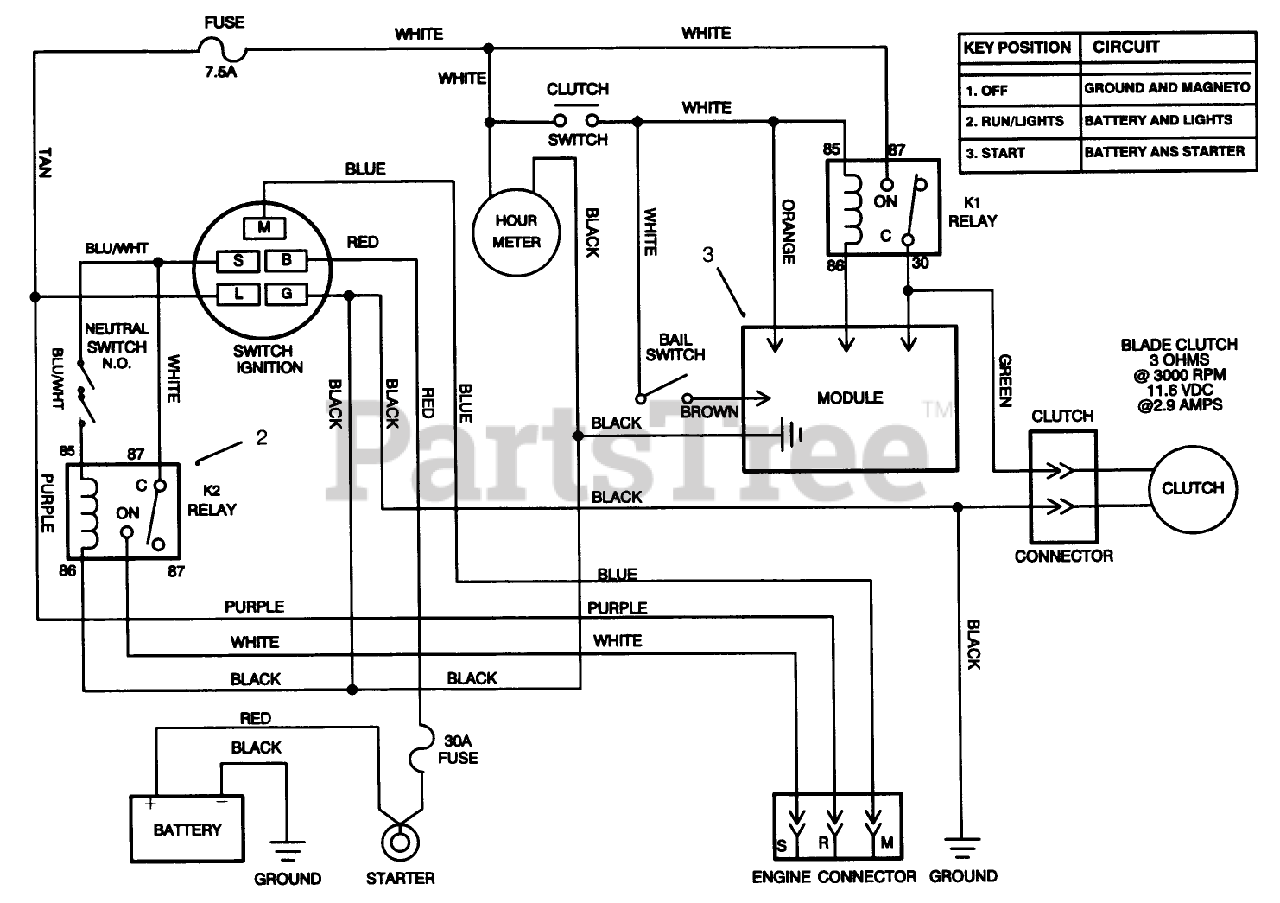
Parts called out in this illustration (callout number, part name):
1	WIRE HARNESS-20HP HYDRO
2	RELAY
3	Module
